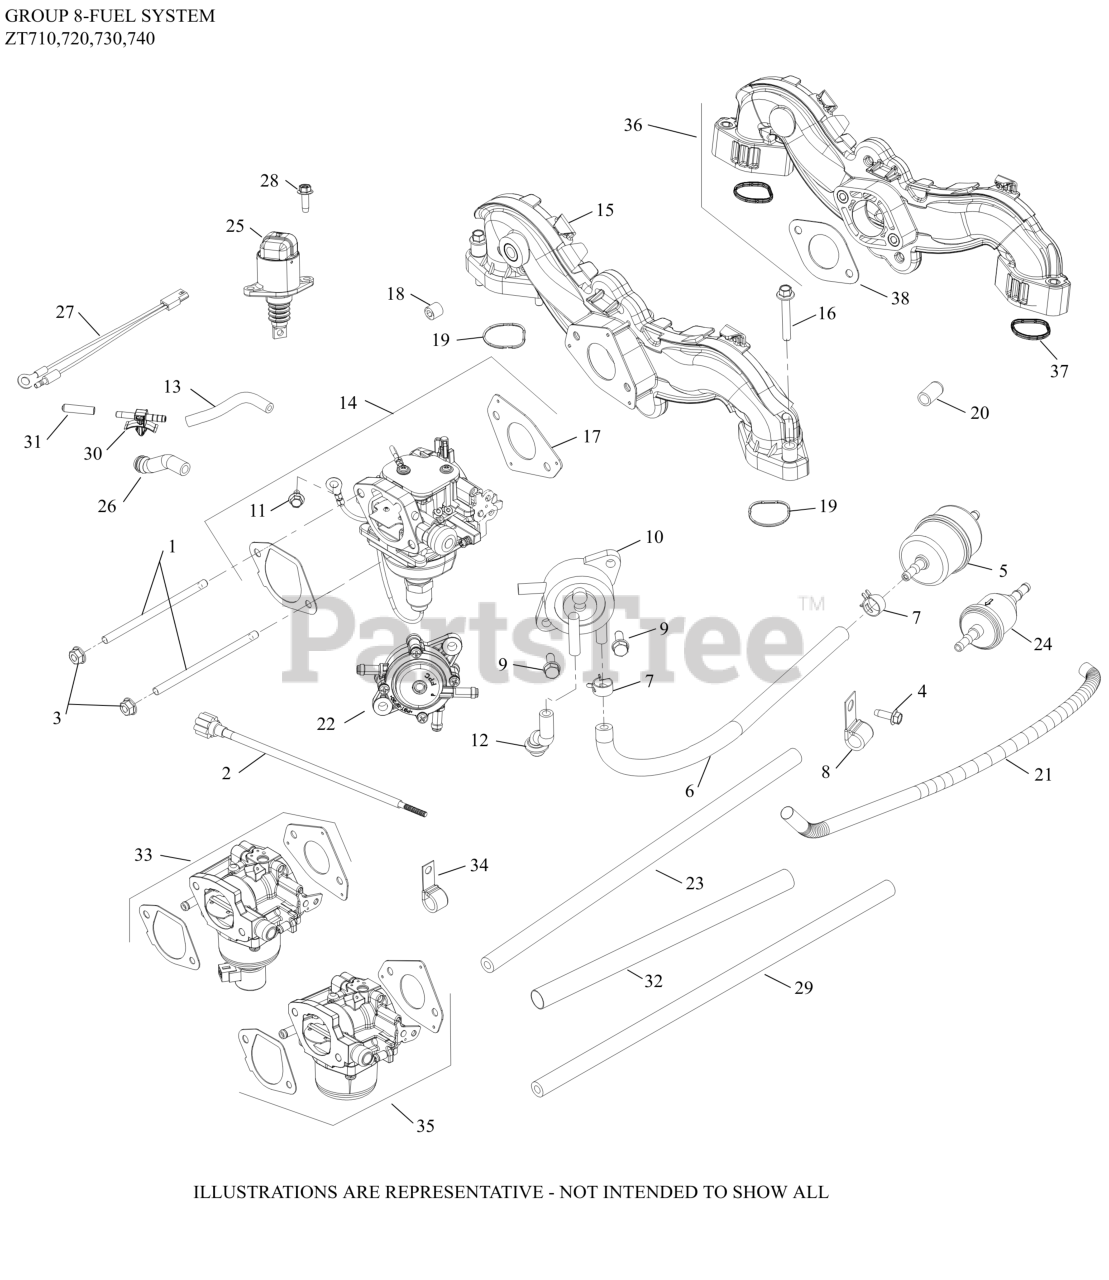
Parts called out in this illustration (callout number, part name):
3	NUT, FLG M6X1.0
5	FILTER, FUEL
6	HOSE,LW PERM.FUEL 24.00"-USE 25 111 81-S
7	SPRING CLAMP, HOSE
9	SCREW, TAP M6X1.7X18
11	SCREW, THREAD FORMING
12	HOSE, PULSE PUMP(STEEL COVERS)
15	KIT, INTAKE MANIFOLD-(#24164277S)
16	SCREW, FLG M6X1.0X40
17	GASKET, CARBURETOR
19	O-RING, INTAKE PORT (PIM)
22	PUMP, FUEL (PULSE)-(#2539326S)
28	SCREW, THREAD FORMING
33	KIT,CARB (NIKKI)
34	CLIP, CABLE (KM)
NI	KIT, OVERHAUL NIKKI G-TYPE TWIN
NI	KIT, BOWL WITH O-RINGS NIKKI G-TYPE TWIN
NI	KIT, FLOAT AND NEEDLE NIKKI G-TYPE TWIN
NI	KIT,THROTTLE SHAFT(22MM)NIKKI G-TYPETWIN
NI	KIT,CHOKE REP(SMART/E-CHOKE)-DISC.
NI	KIT,HIGH ALT(22MM) NIKKI-USE 16 755 19-S
NI	KIT, SOLENOID (NIKKI)
